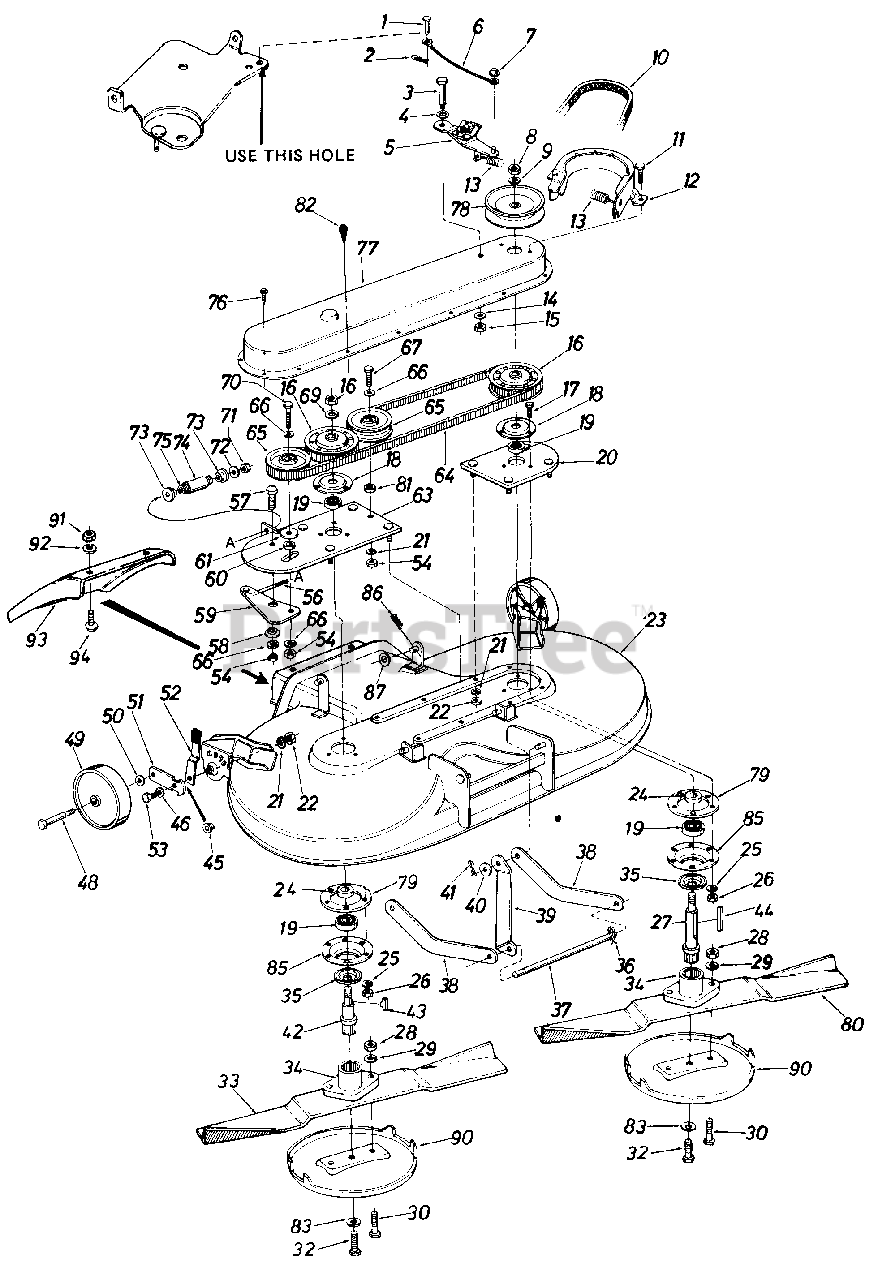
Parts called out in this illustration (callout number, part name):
1	Clevis Pin 1/4" Dia. x 1/2" Lg.
2	Hairpin Cotter 1/4" Dia.
3	Shld. Bolt .437" Dia. x .180" Lg. 5/16-18)
4	Wave Washer 7/16" Scr.
5	Spindle Brake Arm Ass'y.
6	Brake Cable Ass'y.
7	Push Cap 1/4" Stud.
8	Hex Jam Nut 5/8-18 Thd.
9	Bell.-Wash. 5/8" I.D. x 1.25" O.D.
10	"V" Belt
11	Hex Wash. Hd. Self Tap Scr. 1/4-20 x .50" Lg.
12	Belt Guard
13	Extension Spring
14	Bell.-Wash. .340" I.D.
15	Hex Cent. L-Nut 5/16-18 Thd.
16	Sprocket Pulley Ass'y.
17	Hex Bolt 5/16-24 x 1.00" Lg. (Grade 5)
18	Bearing Housing
19	Ball Bearing .787" I.D. x 1.85" O.D.
20	Spindle Plate Ass'y.
21	L.-Wash. 3/8" I.D.*
22	Hex Jam Nut 3/8-24 Thd.
23	44" R.D. Deck Ass'y.
25	L.-Wash. 5/16" I.D.*
26	Hex Nut 5/16-24 Thd.*
27	Blade Spindle-L.H.
28	Hex Nut 5/16-24 Thd.
29	L.-Wash. 5/16" I.D.*
30	Hex Bolt 5/16-24 x 1.00" Lg.
32	h'ex Bolt Cent. L.-3/8 x 24 0 x 88" Lg.
33	22.5" Blade-L.H. Rotation
34	Blade Adapter
35	Bearing Shield
36	Hairpin Cotter
37	Deck Connecting Rod
41	Cotter Pin 3/32" Dia. x 1.00" Lg.*
42	Blade Spindle-R.H.
43	Sq. Key 3/16" x 75" Lg.*
44	Sq. Key 3/16" x 1.50" Lg.*
45	Shoulder Spacer
46	Bell.-Wash. .400" I.D.
48	Shld. Bolt 3/8-16 x 1.41" Lg.
49	Wheel Ass'y. Cornp. 6" x 1.38
50	Bell-Wash. 3/8" I.D.
51	Wheel Pivot Bar
52	Spring Lever Ass'y. w/knob
53	Hex Bolt 3/8-24 x 1.25" 4. Grade 5
54	Hex Cent. L-Nut 3/8-24 Thd.
56	Adjustment Link 5/16-18 x 4-9/16" Lg.
57	Hex Bolt 3/8-24 x 1.00"
58	Shld. Spacer.625" I.D.
59	Belt Idler Brkt.
60	Spacer.380" I.D. x.625" O.D. x .265
61	Fl.-Wash. .38" I.D. x 1.37" O.D. x .125
63	Spindle & Idler Mount Plate Ass'y.
64	HTD Twin Power Belt
65	Fl.-ldler Pulley 3.50" O.D.
66	Bell.-Wash. .38" I.D.
67	Hex Bolt 3/8-24 x 1.75" Lg. (Grade 5)
69	Bell.-Wash. 5/8" I.D.
70	Hex Bolt 3/8-24 x 2.00" Lg.
71	Hex Insert L.-Nut5/16-18Thd.
72	Fl.-Wash. 344" I.D. x 1.125" O.D. x .125
73	Shld. Spacer.625" I.D.
74	Spacer-Adj. Bolt
75	Compression Spring
76	Hex Wash. Hd. Self Tap Scr. 1/4-20 x .50" Lg.
77	Belt Cover
78	Deck Drive Pulley
79	Deck Reinforcement Plate
80	22.5" Blade-R.H. Rotation
81	Fl.-Wash. .38" I.D. x 1.00" O.D.
82	Hex Wash. Hd. Self Tap-Scr. 1/4-20 x .75" 4.
83	L.-Wash. 3/8" I.D. Heavy Duty
86	Hairpin Cotter
87	Fl.-Wash. 1/2" I.D.
90	Anti Scalp Plate
91	Hex Nut 1/4-20 Thd.*
92	L.-Wash. 1/4" I.D.*
93	Chute Deflector
94	Truss Mach. Scr. 1/4-20 x .50" Lg.
